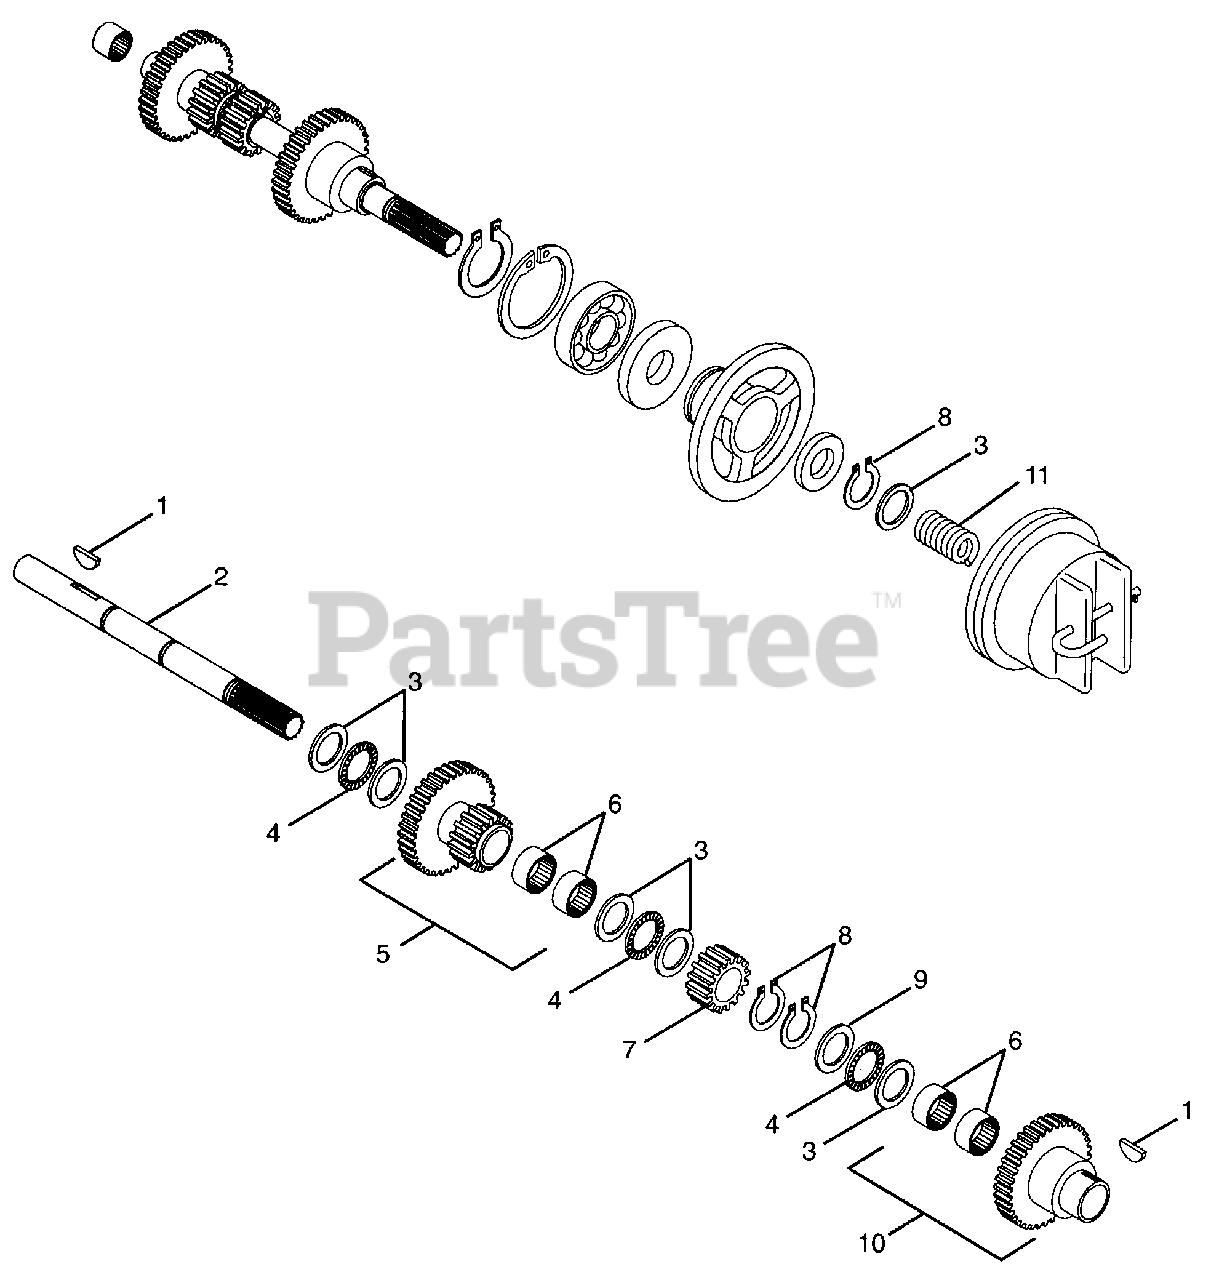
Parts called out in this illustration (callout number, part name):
1	Key-Woodruff .19 x .63
2	Shaft-Splined Reverse Clutch
3	Bearing-N-Thrust .752 x 1.24 x .031
4	Bearing-N-Thrust .754 x 1.24 x .078
5	Gear-Idler Assembly
6	Bearing-Roller .75 x 1.0 x .50
7	Gear 10 DP 16 Teeth x .750
8	Ring-Retaining-Internal .750 x .042
9	Washer-Thrust .752 x 1.240 x .062
10	Assembly Reverse Gear & Bearing
11	Spring-Compression .085 x .80 x 1.00
